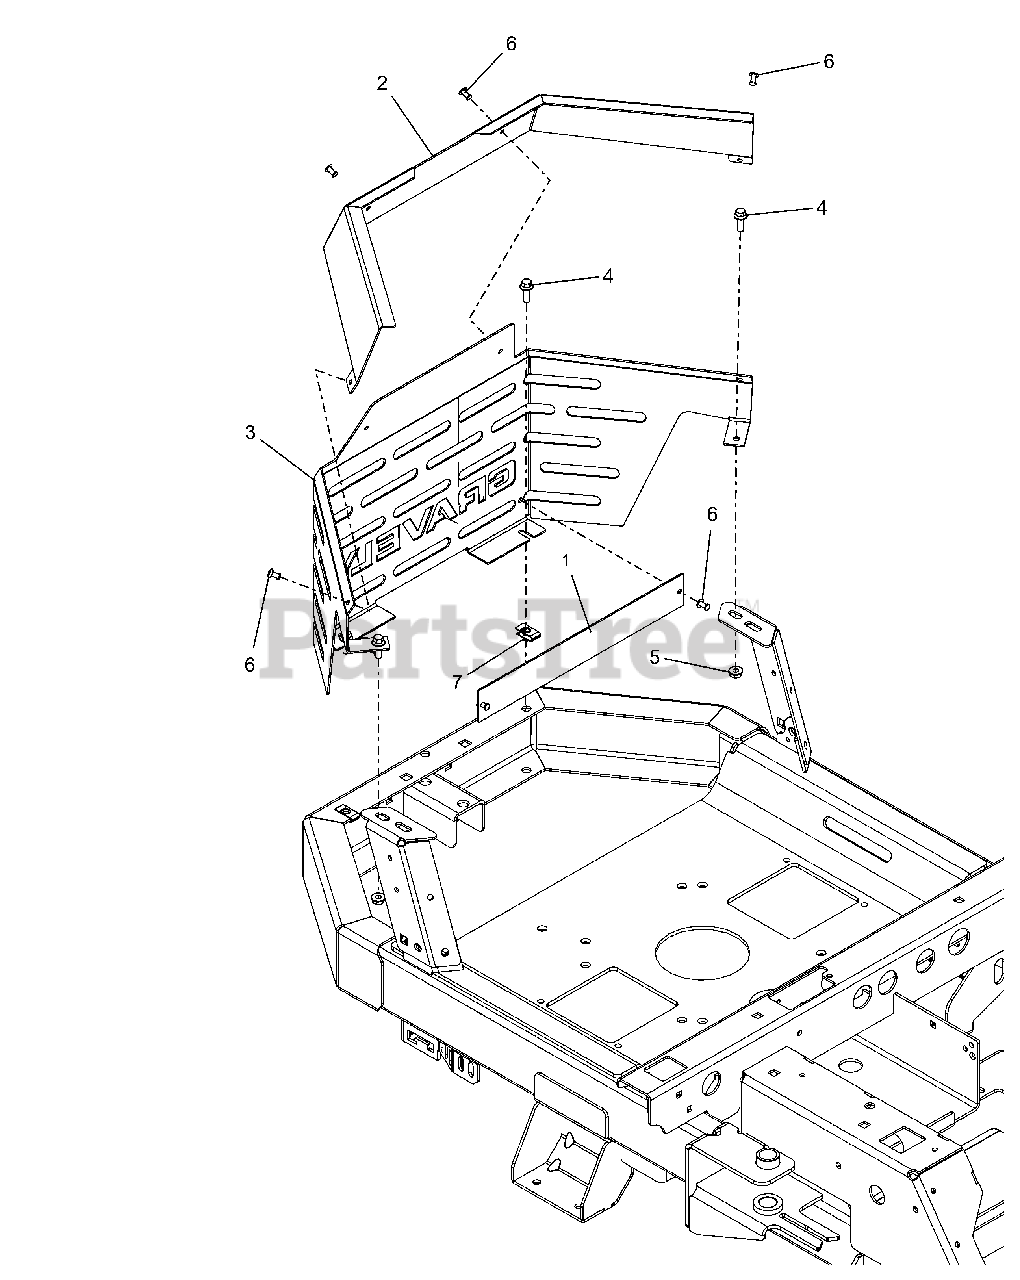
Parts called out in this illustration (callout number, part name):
1	PLATE, SHROUD BACKER
2	WLDMT, ENGINE SHROUD TRIM-XL
3	SHROUD, ENGINE - GRAVELY XL
4	BLT,HEX-FLG .25-20X.75 G5 BFP
5	NUT-LK-TOP-FLG .250-20 GF ZCC
6	RIVET, #66 STEEL POP PD BLACK
7	NUT-RTNR .25-20X.56
